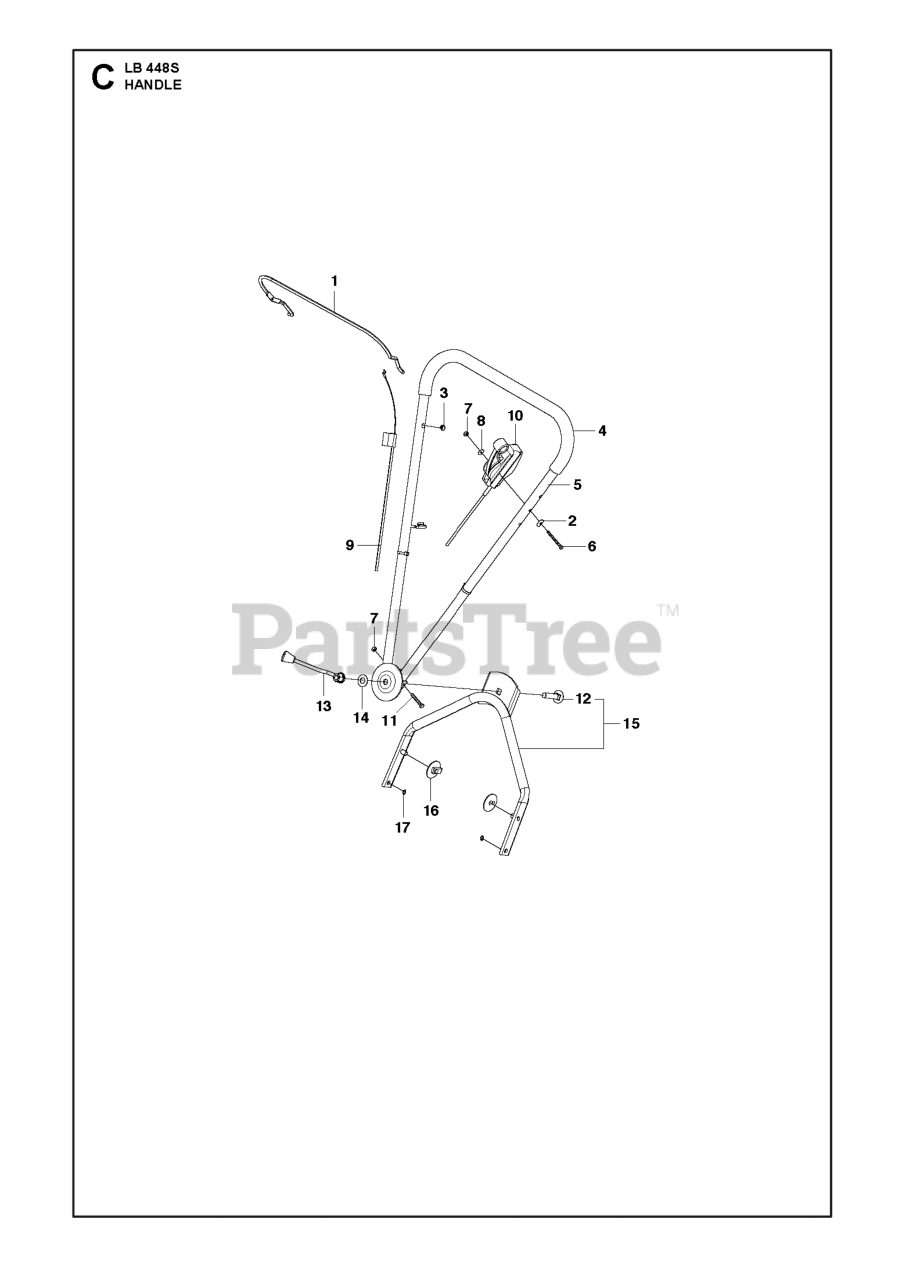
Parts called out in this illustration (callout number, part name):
6	SCREW M6X55
7	NUT FLANGE - M6
11	Hex Head Capscrew, M6 X 1.00 X 40MM
17	RETAINING RING SGA 10
